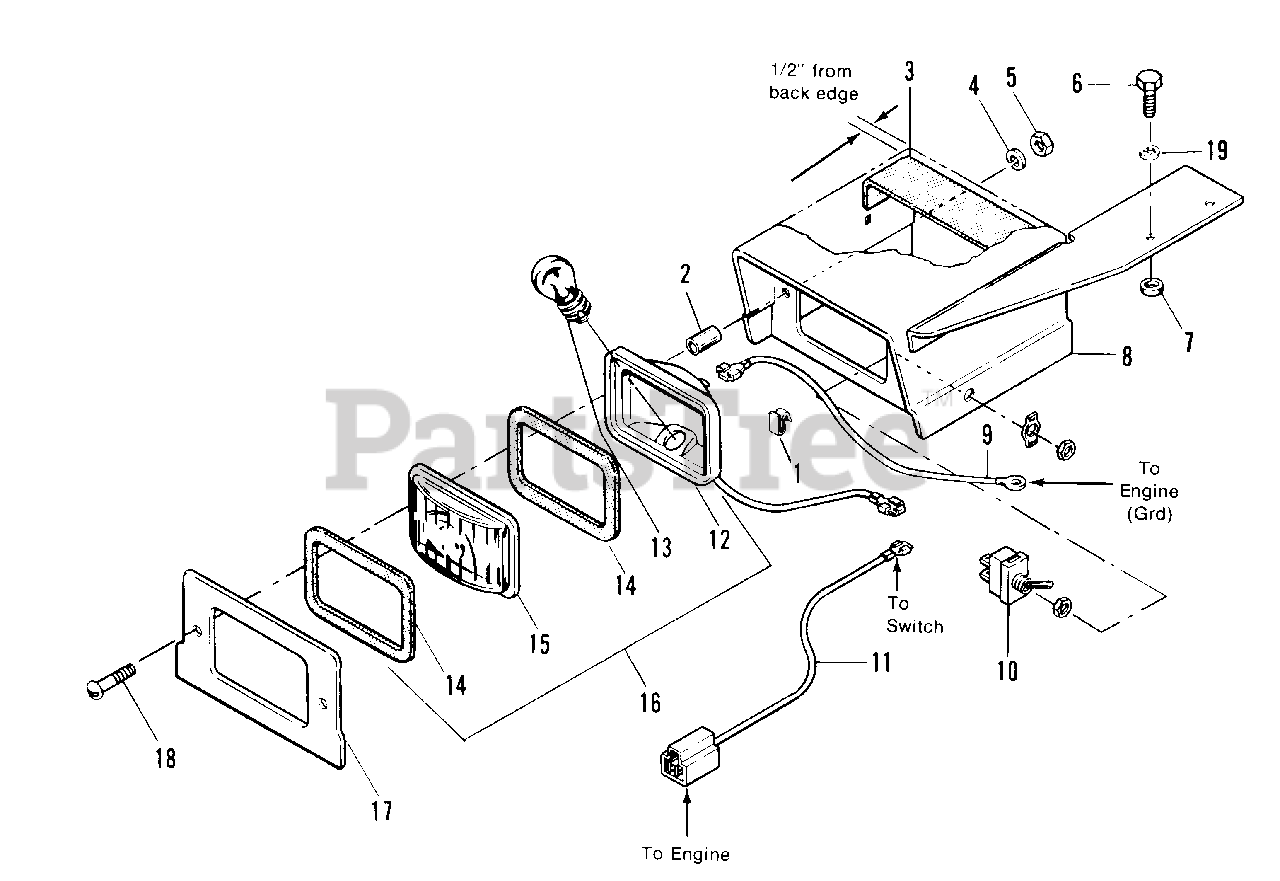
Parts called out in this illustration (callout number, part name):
1	CLIP, Wire
3	PAD, Rubber
4	LOCKWASHER, 1/4
5	NUT, Hex, 1/4-20
6	CAPSCREW, Hex Hd., 5/16-18 x 1
7	WASHER, Plain, 5/16 x 1 O.D.
8	COVER ASSY., Headlight
9	WIRE, Light to Ground
10	SWITCH, Toggle (Incl. washer & nuts)
11	WIRE, Engine to Switch
12	SOCKET, Reflector
15	LENS, Amber
16	LIGHT ASSY. (Incl. Ref. Nos. 12 thru 15)
17	SUPPORT, Light
18	SCREW, Rd. Hd., 1/4-20 x 1
19	LOCKWASHER, Internal Tooth, 5/16
